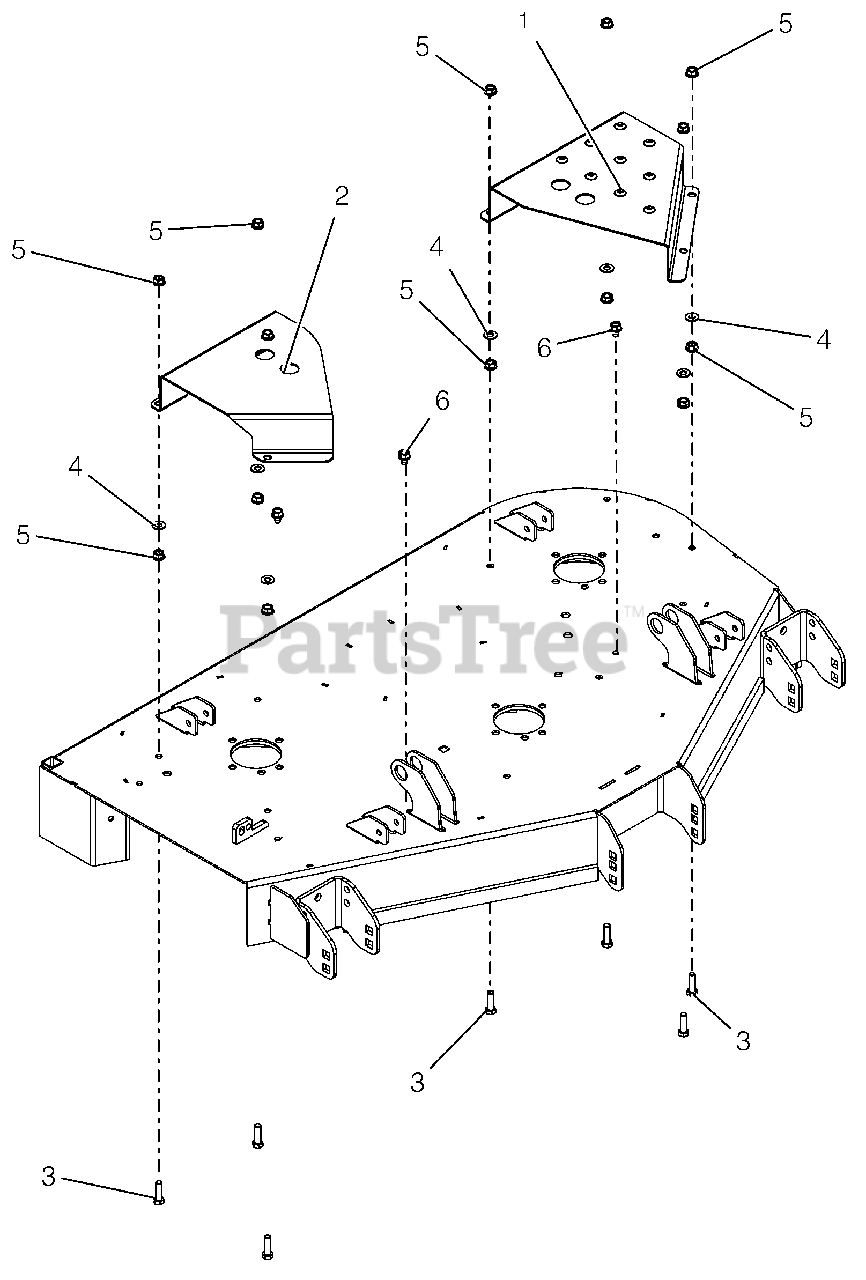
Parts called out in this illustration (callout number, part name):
1	COVER, BELT 44" LH
2	COVER, BELT 44" RH
3	@BLT-HEX .38-16X1.25 GR5 YWZC
4	@WSHR-FL-STL.406X.812X.065 YWZ
5	@NUT-SPNLK-FLG .375-16 YWZC
6	@SCR-TAP .38-16X.50 HWH TR YWZ
